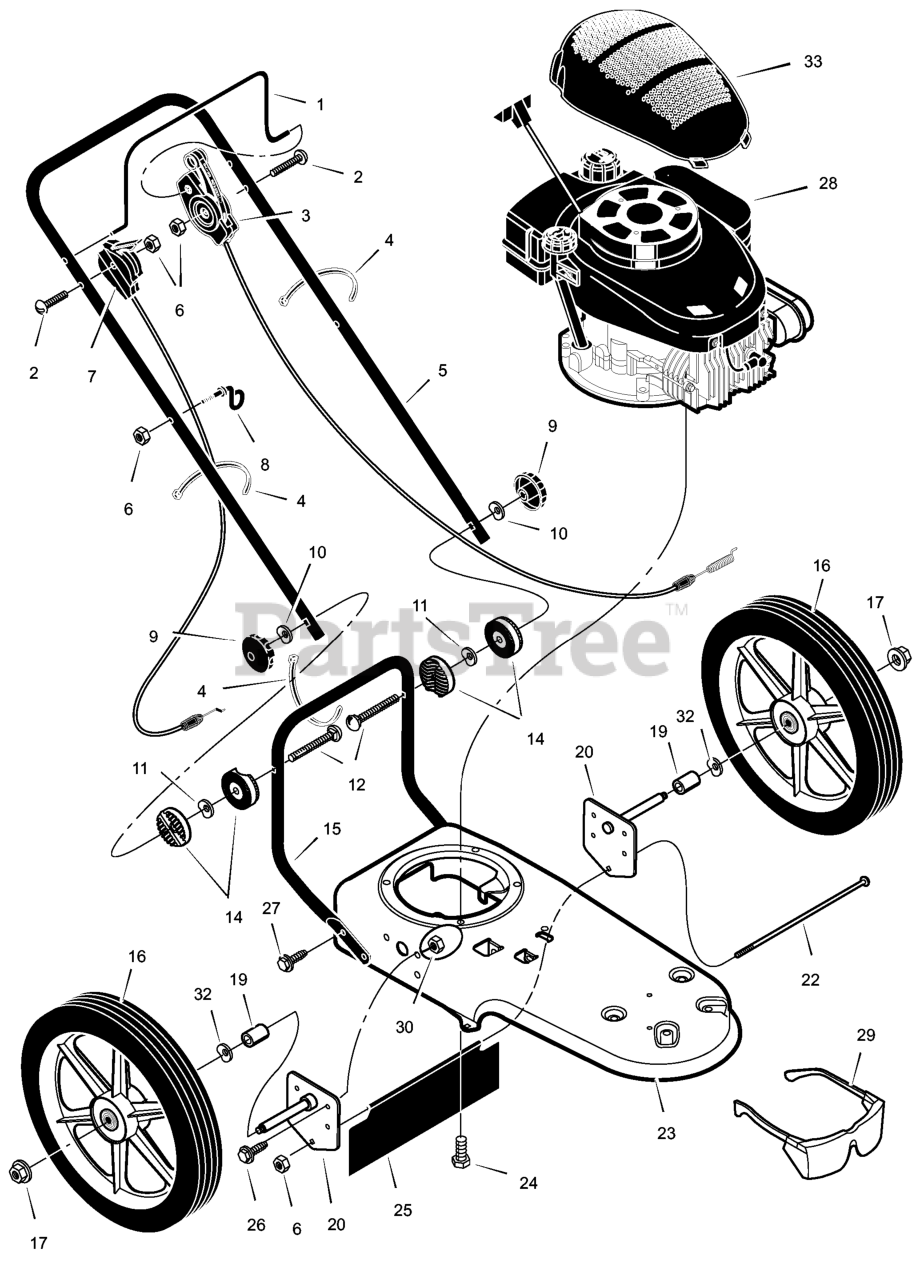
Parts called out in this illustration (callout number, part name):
1	Lever, Stop
3	Cable, Control Latching
4	Tie, Cable
5	Handlebar
6	Nut
7	Control, Throttle
8	Guide, Rope
9	Knob, Handlebar
11	Washer, Spring
14	Pivot, Handlebar
15	Handlebar, Lower
16	Wheel & Tire
17	Nut, Axle
18	Washer, Spring
20	Assembly, Axle & Bracket
22	Bolt, Carriage
25	Shield, Trailing
26	Bolt
28	Engine
29	Glasses, Safety
30	Nut
32	Washer, Spring
33	Shroud, Engine
